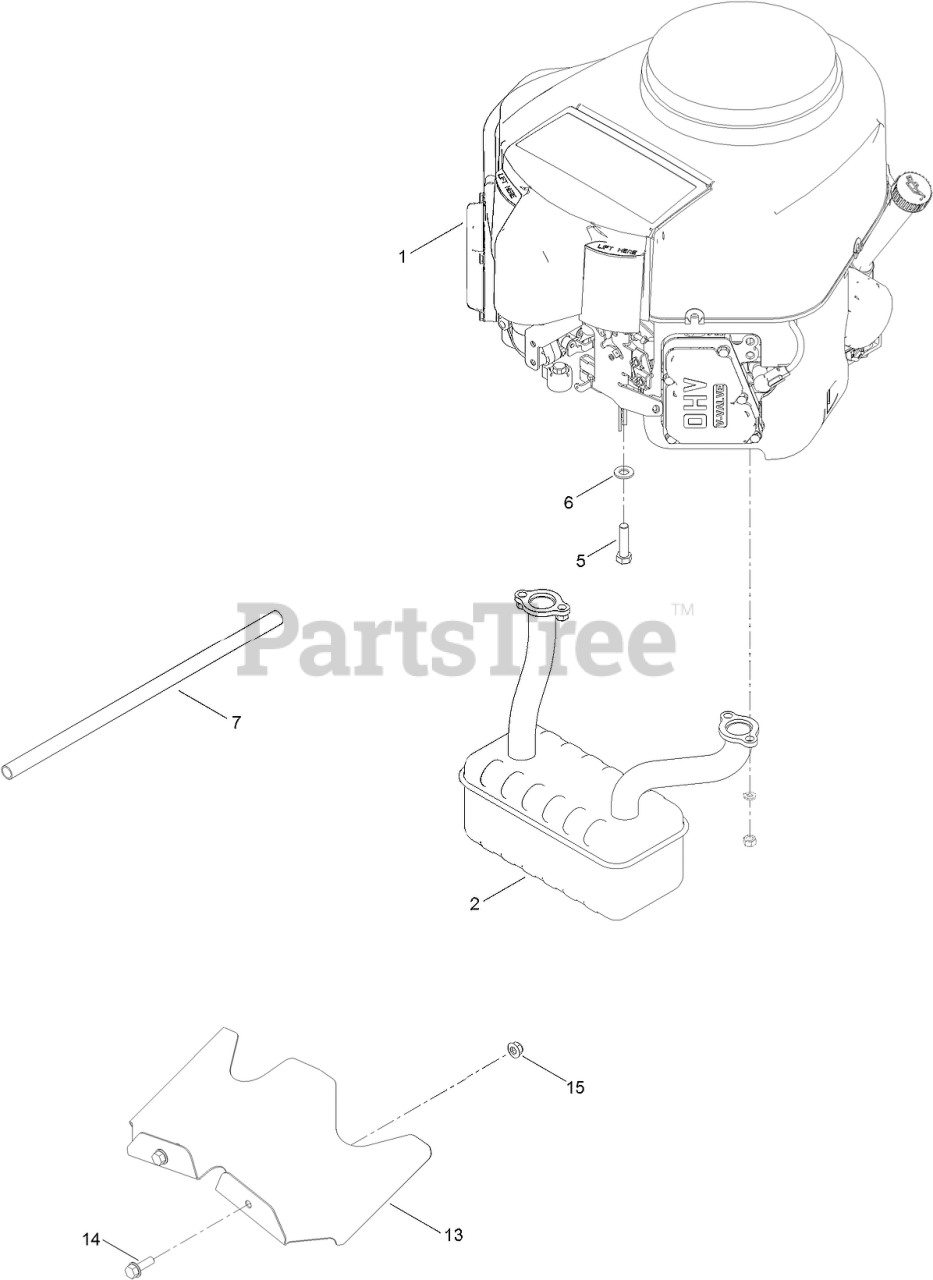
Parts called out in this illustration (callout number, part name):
2	MUFFLER
5	BOLT-HH
6	WASHER-FLAT
7	TUBE-DRAIN, OIL
13	SHIELD-HEAT
14	SCREW-HHF
15	NUT-HF, NI
